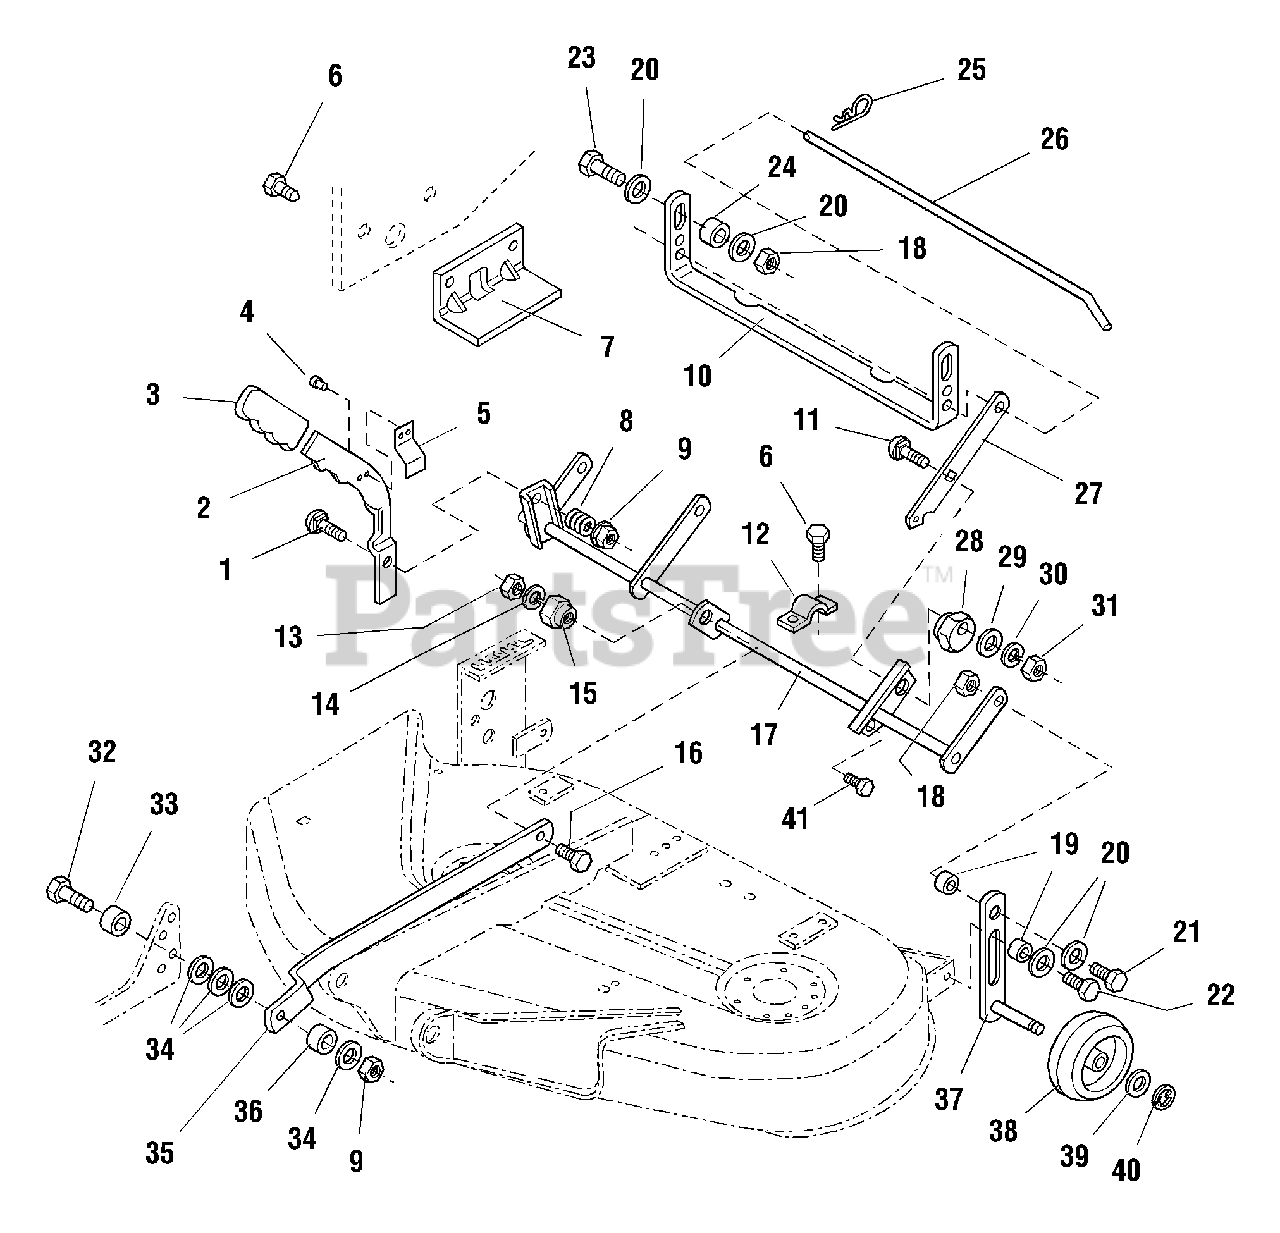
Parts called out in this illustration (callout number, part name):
1	CARRIAGE BOLT, 3/8-16 x 1-3/4
2	ADJUSTMENT ARM
5	SPRING, Handle
6	CAPSCREW, Hex Washer Hd, Taptite, 5/16 - 18 x 3/4
7	BRACKET, Upstop
9	NUT, Hex Flange Whiz Lock, 3/8-16
10	BRACKET, "U"
11	CARRIAGE BOLT, 5/16-18 x 1-1/4
12	STRAP
13	NUT, Hex, Full, 3/8-16
14	LOCKWASHER, 3/8
15	NUT, Hex Adjusting, .99 DIA .687
16	CARRIAGE BOLT, 3/8-16 x 1-1/2
17	ROCKER ARM ASSEMBLY
18	NUT, Hex Lock, 5/16-18
20	WASHER, 5/16
21	CAPSCREW, Hex Hd, 5/16-18 x 1
22	CAPSCREW, Taptite Hex Washer Hd, 5/16-18 x 1
23	CAPSCREW, Hex Hd, 5/16-18 x 1-1/4
25	CLIP, Spring
26	ROD, Transport
29	WASHER, Flat, 5/16
30	LOCKWASHER, 5/16
31	NUT, Hex, Full, 5/16-18
32	CAPSCREW, Hex Hd., 3/8-16 x 2, Grade 5
34	WASHER, Plain, 3/8
37	ARM ASSEMBLY
38	GAUGE WHEEL
39	WASHER, 1/2
40	RETAINING RING
41	CAPSCREW, Hex Washer Hd, Taptite, 5/16 - 18 x 7/8
